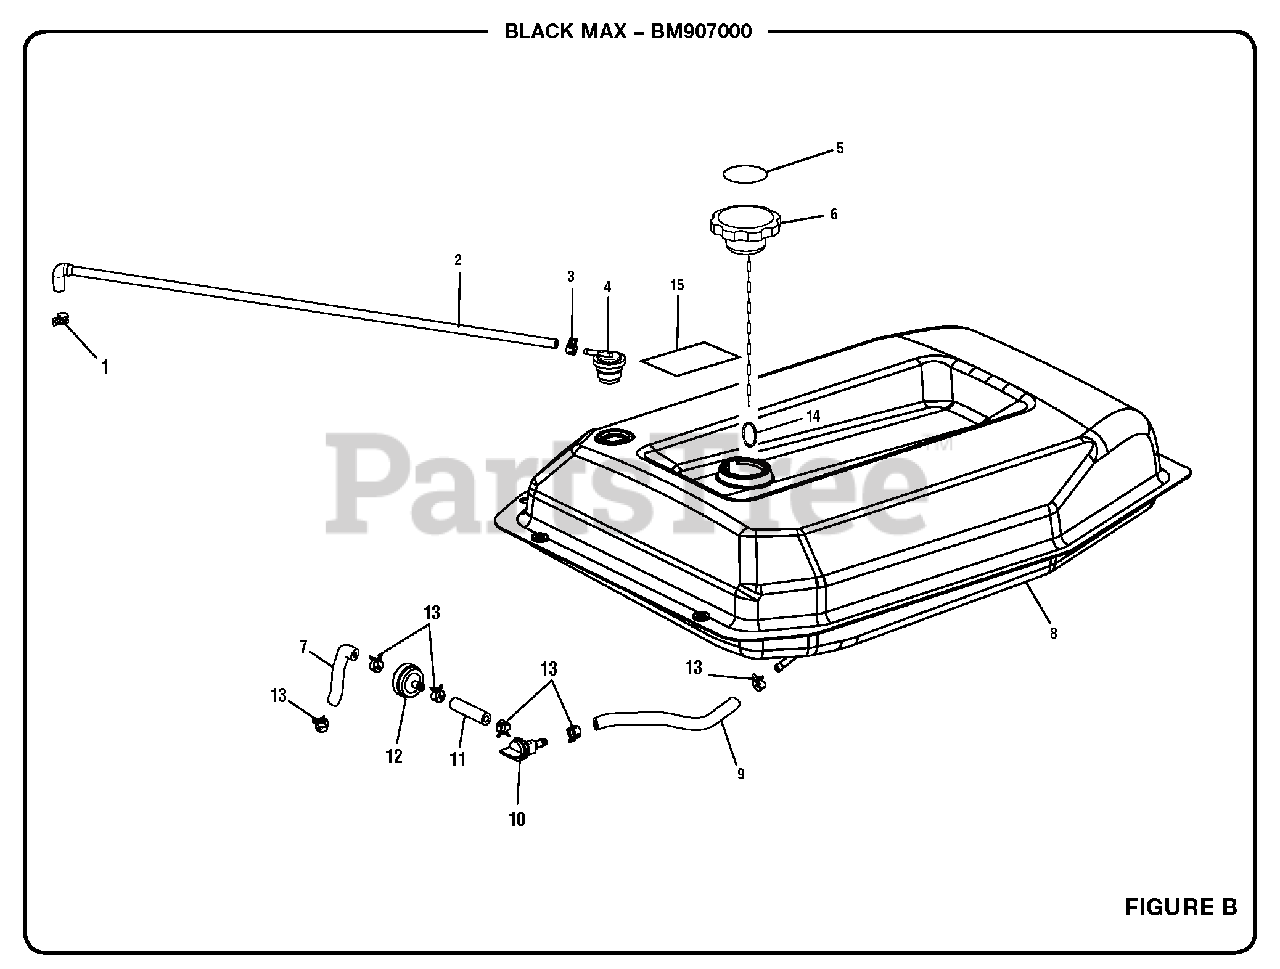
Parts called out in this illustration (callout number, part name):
1	Fuel Line Clamp (10.3 mm)
2	Vapor Hose (590 mm and 30 mm)
3	Fuel Line Clamp (3/8 in)
4	Vapor Vent
5	Fuel Stabilizer Label
7	Fuel Hose (185 mm)
8	Fuel Tank
9	Fuel Hose (175 mm)
10	Fuel Valve
11	Fuel Hose (55 mm)
12	Fuel Filter
13	Fuel Line Clamp (1/2 in)
14	Ring Clip
15	Fuel Stabilizer Label (Spanish)
